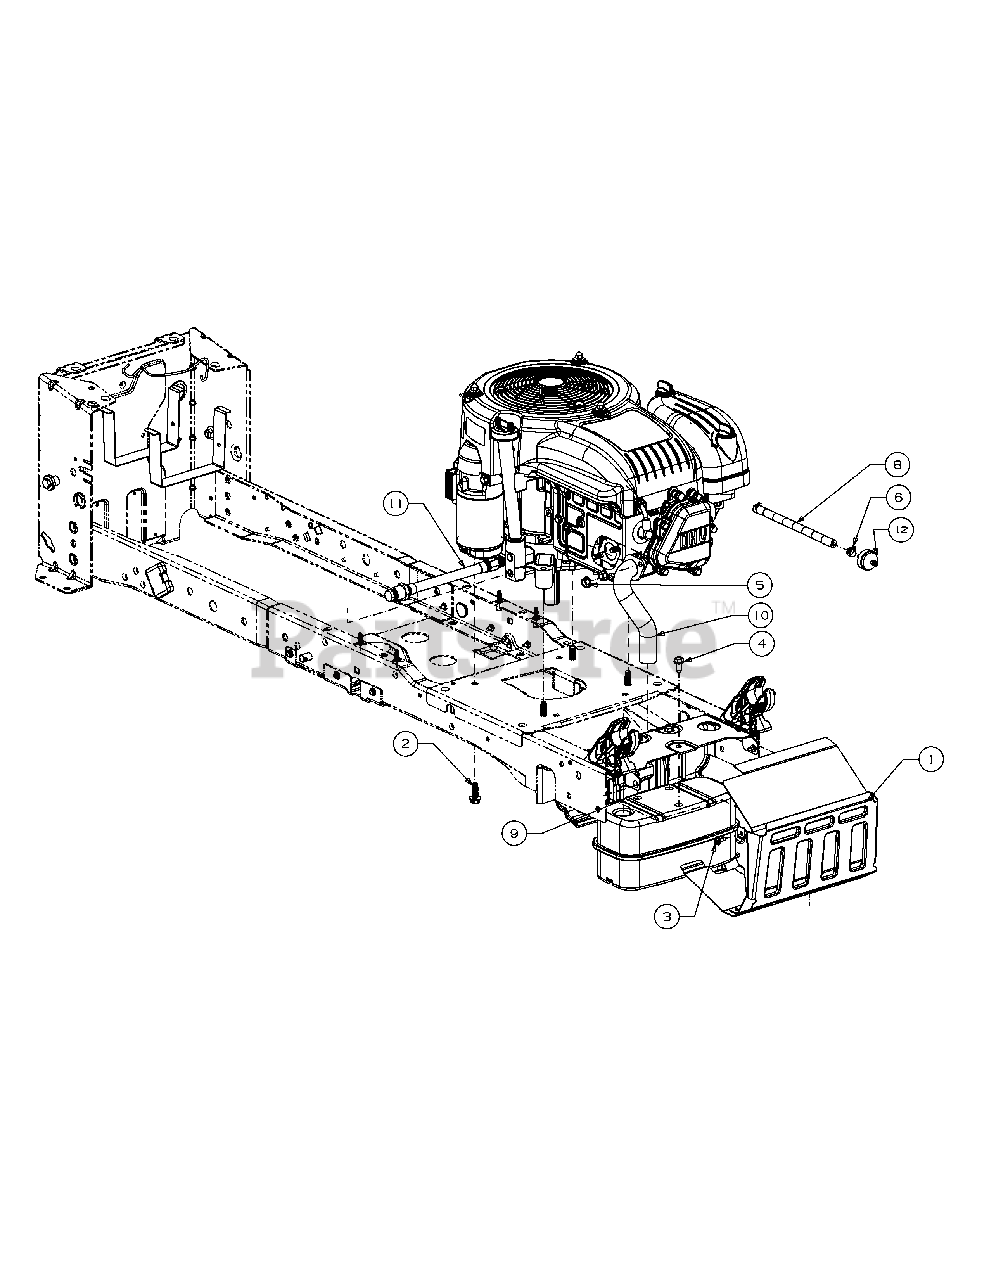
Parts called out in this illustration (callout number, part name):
1	Shield Asm, Exhaust Heat
2	Screw-Hxindwsh Tt 3/8-16 X 1.0
3	Screw-Hxacrnwsh M6-
4	Screw-Hxindwsh Tt M8
5	Nut-Hex Flange M8X
6	Hose Clamp 1/20
7	Oil:Sae 10W30
8	Hose:Fuel Low Perm
9	Muffler-Exhaust
10	Pipe, Exhaust
11	Hose-Oil Drain
12	Filter, Fuel
